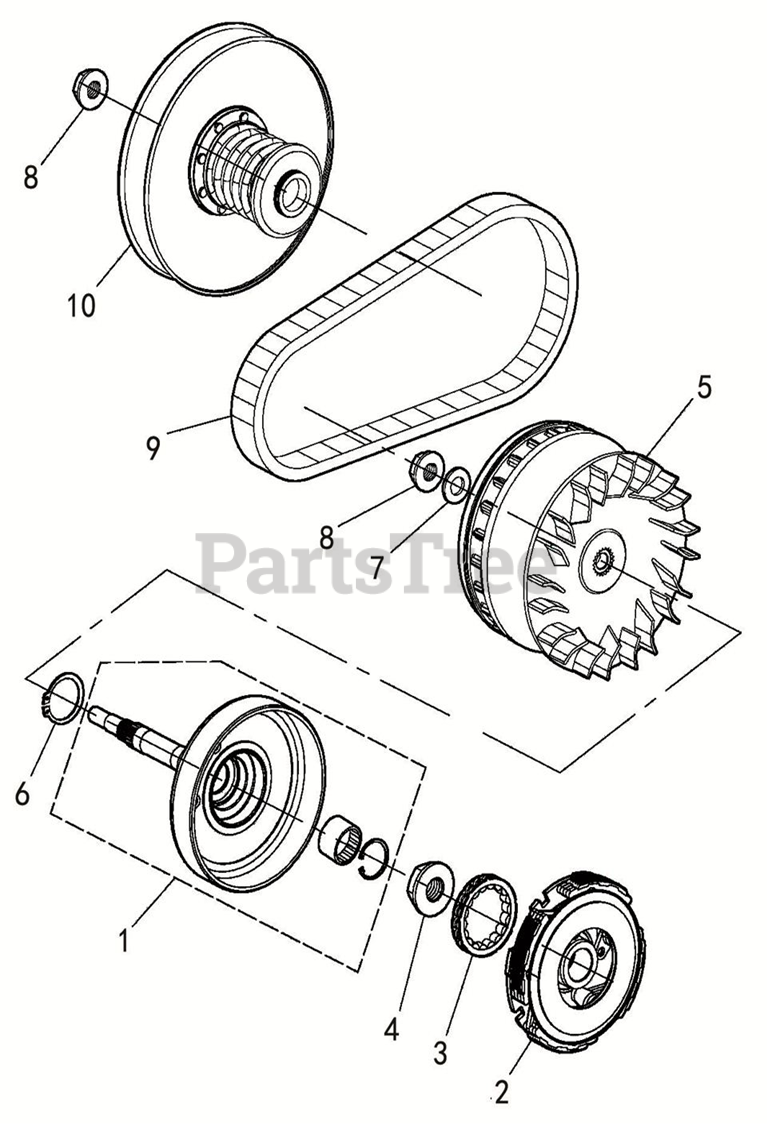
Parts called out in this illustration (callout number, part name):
1	CLUTCH DRUM ASSEMBLY
2	CLUTCH SHOE
3	OVERRUNNING CLUTCH ASSEMBLY
4	HEX FLANGE NUT M22X1
5	PRIMARY DISC ASSEMBLY
7	WASHER 19.2X35X3.2
8	HEX FLANGE NUT M16X1
10	DRIVEN PULLEY ASSEMBLY
